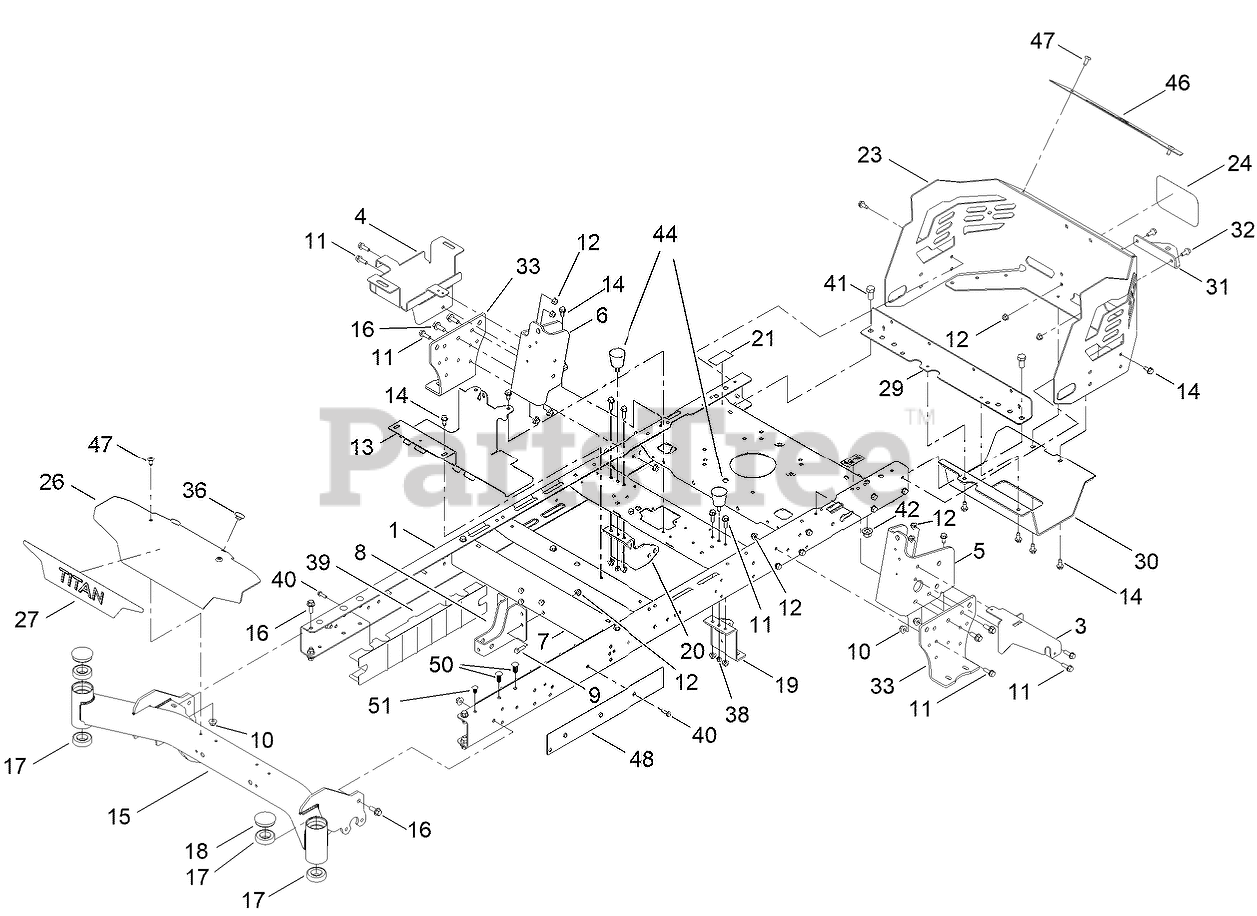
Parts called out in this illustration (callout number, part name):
1	FRAME ASM
3	BRACKET-SUPPORT, POD (LH)
4	TRAY-BATTERY
5	BRACKET-MOUNTING, LH
6	BRACKET-MOUNTING, RH
7	BRACE-CROSS, LOWER
8	BRACKET-MOUNT DAMPER, LOWER
9	SCREW-HH
10	NUT-HF, NI
11	SCREW-HHF
12	NUT-HF, NI
13	BRACKET-MOUNT
14	SCREW-HWHTF
15	FRONT AXLE ASM
16	SCREW-HHF
17	BEARING-BALL
18	CAP-GREASE
19	MOUNT-HYDRO, FRONT (LEFT)
20	MOUNT-HYDRO, FRONT (RIGHT)
21	DECAL-BYPASS
23	GUARD-ENGINE
24	DECAL
26	PLATE-FRONT
27	DECAL-TITAN
29	CROSSMEMBER-REAR, WIDE
30	GUARD-MUFFLER
31	BRACKET-HITCH
32	SCREW-HHF
33	MOUNT-HYDRO
36	BUMPER-SEAT
38	NUT-LOCK, NI
39	GUARD-RAIL
40	SCREW-HWH
41	SCREW-HH
42	NUT-LOCK
44	BUMPER-RUBBER
46	TRIM-GUARD, ENGINE
48	PLATE-FRAME
50	RIVET-PUSH
51	RIVET-PUSH
